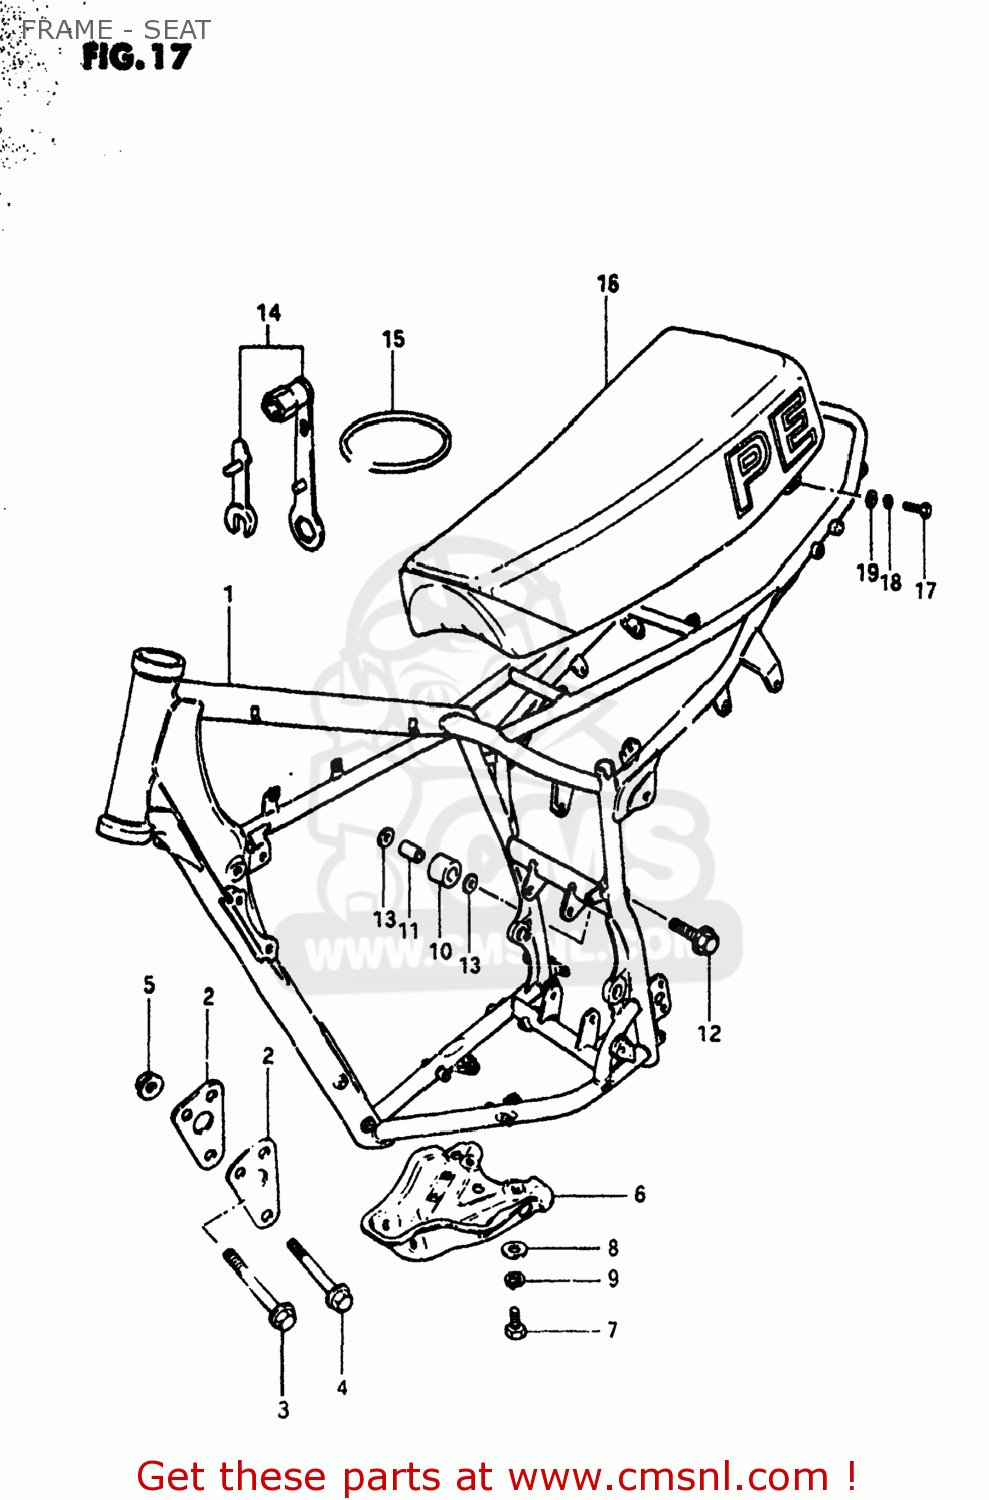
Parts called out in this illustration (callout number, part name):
1	FRAME
2	PLATE,ENGINE MOUNTING
3	BOLT(8X67)
4	BOLT
5	NUT
6	PROTECTOR,ENGINE
7	BOLT
8	WASHER (8.2X20X1.6)
9	LOCK WASHER
10	ROLLER,CHAIN CONTROL
11	SPACER,CHAIN LENGTH ROLLER
12	BOLT(8X45)
13	WASHER
14	SPARK PLUG WRENCH
15	O RING TOOL FITTING
16	SEAT ASSEMBLY
17	BOLT
18	LOCK WASHER
19	WASHER (8.2X20X1.6)
